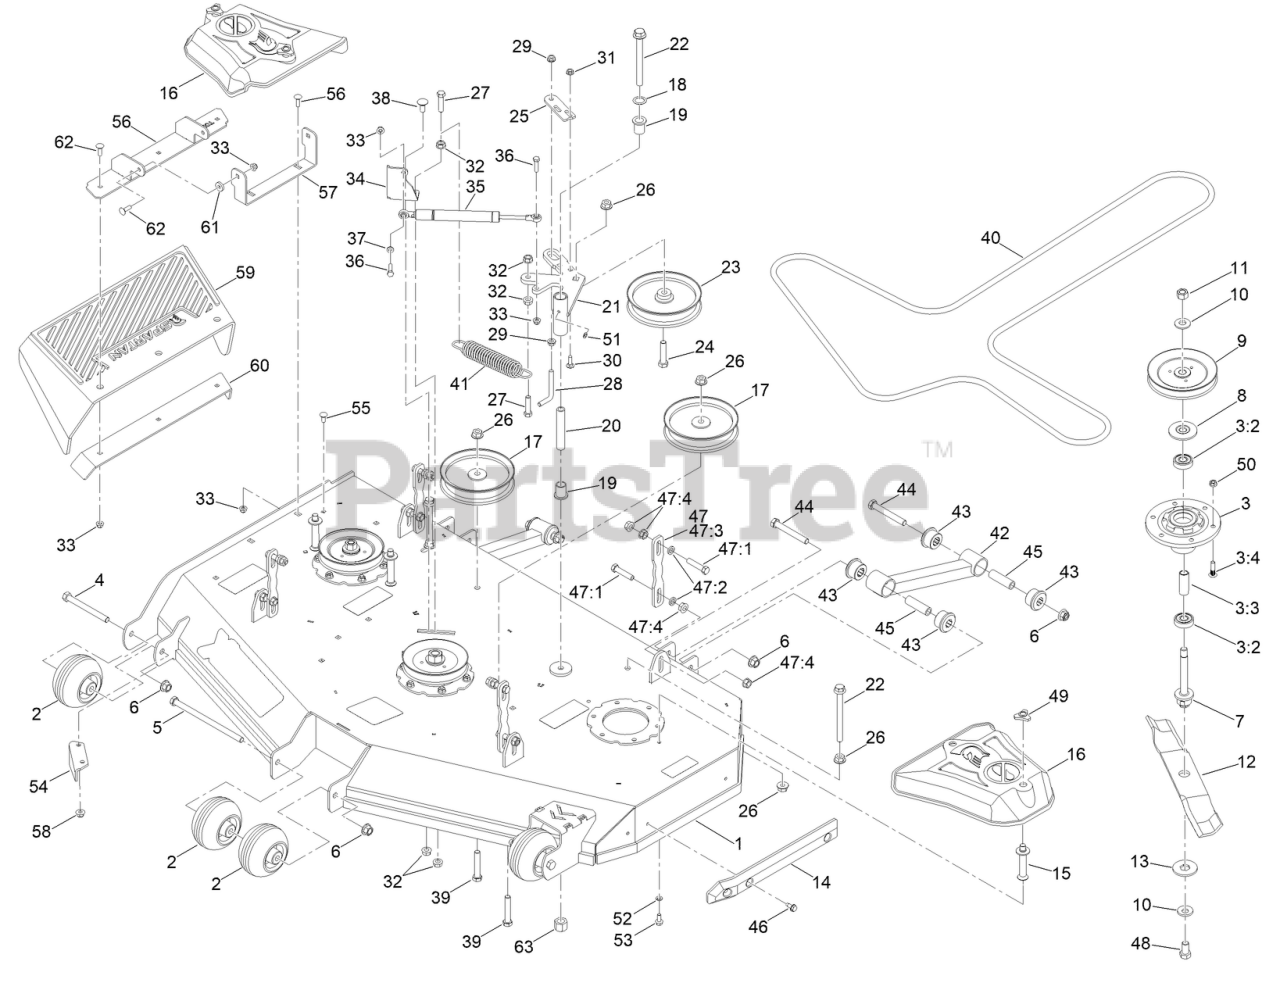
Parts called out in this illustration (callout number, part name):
1	54 INCH DECK ASM W/DECALS
2	MWR ANTI-SCALP WHL W/O GREASE FITTING
3	SPINDLE ASM 5IN DECK
3:2	BEARING
3:3	SPACER, BEARING
3:4	BOLT-ROUND HEAD
4	SCREW-HH
5	1/2-13 X 8-1/2 HEX C/S GR 2 ZINC YELLOW
6	NUT-LOCK
7	SHAFT - SPINDLE
8	GUARD-BEARING TOP 0.673IN
9	PULLEY
10	M16 SPRING WASHER (39MMOD/ 3.9MM THK)
11	M16X1.5 C8.8 HEX NUT
12	BLADE-ROTARY
13	WASHER-HEX
14	MWR NYLON DECK GUARD
15	PIN-BELT COVER
16	COVER BELT
17	6-3/4IN IDLER PULLEY 15/16IN SPACER ASSY
18	.767IDX1.125ODX.016 THK TRIP WV WASHER
19	3/4IN ID X15/16IN OD X 1-1/8IN FLNG BUSH
20	MWR INNER IDLER SPACER
21	MWR DECK IDLER PULLEY ARM ASSY PAINT
22	1/2-13 X 5-1/2 HEX FLANGE BOLT GR 8 ZY
23	6-3/4IN IDLER PULLEY 7/16IN SPACER ASM
24	SCREW-HH
25	DECK IDLER PULLEY BELT RETNR BRKT PAINT
26	NUT-HHF
27	SCREW-HH
28	BOLT-L
29	3/8-16 HEX FLANGE NUT W/SERR ZINC YELLOW
30	BOLT-CARR
32	NUT-HF
33	NUT-HF, NI
34	DECK BELT IDLER DAMPER MTG BRKT PAINTED
35	IDLER GAS SPRING
36	SCREW-HH
37	.312IDX.625ODX.062 THK THRUST BRG OI BRZ
38	SCREW-CARR
39	1/2-13 X 2-3/4 HEX FLANGE BOLT (GR.8) YZ
40	54 DECK BELT
41	MWR DECK SPRING
42	RZ MWR DECK STABLZR ASSY
43	RED A80 SUSP BUSHING
44	1/2-13 X 3-3/4 HEX C/S (GR.5) ZC/YEL
45	UTV A-ARM BUSHING SLEEVE
46	SCREW-HWH, THREAD CUT
47	RZ MWR DECK LINK ASM
47:1	SCREW-HH
47:2	.443 ID X .749 OD X .125 THK NYLON BLACK
47:3	RZ MWR DECK ACTUATOR CONN LINK PAINT
47:4	NUT-HF
48	M16X1.5-30MM C10.9 HEX BOLT
49	NUT-KNOB
51	1/4IN DRIVE TYPE GREASE FITTING YZ
52	WASHER-LOCK
53	SCREW-HHF
54	BAFFLE-DISCHARGE
55	SCREW-CARR
56	DECK CHUTE HINGE ASM
57	BRACKET-CHUTE
58	NUT-HF, NI
59	RZ MWR RUBBER DISCHARGE CHUTE
60	MWR DECK CHUTE HINGE BACKER BRKT
61	.312 ID X .875OD X .1875 THK F/W NYL
62	5/16-18 X 1 CARRIAGE BOLT GR 8 YZ
63	NUT-LOCK, NI
